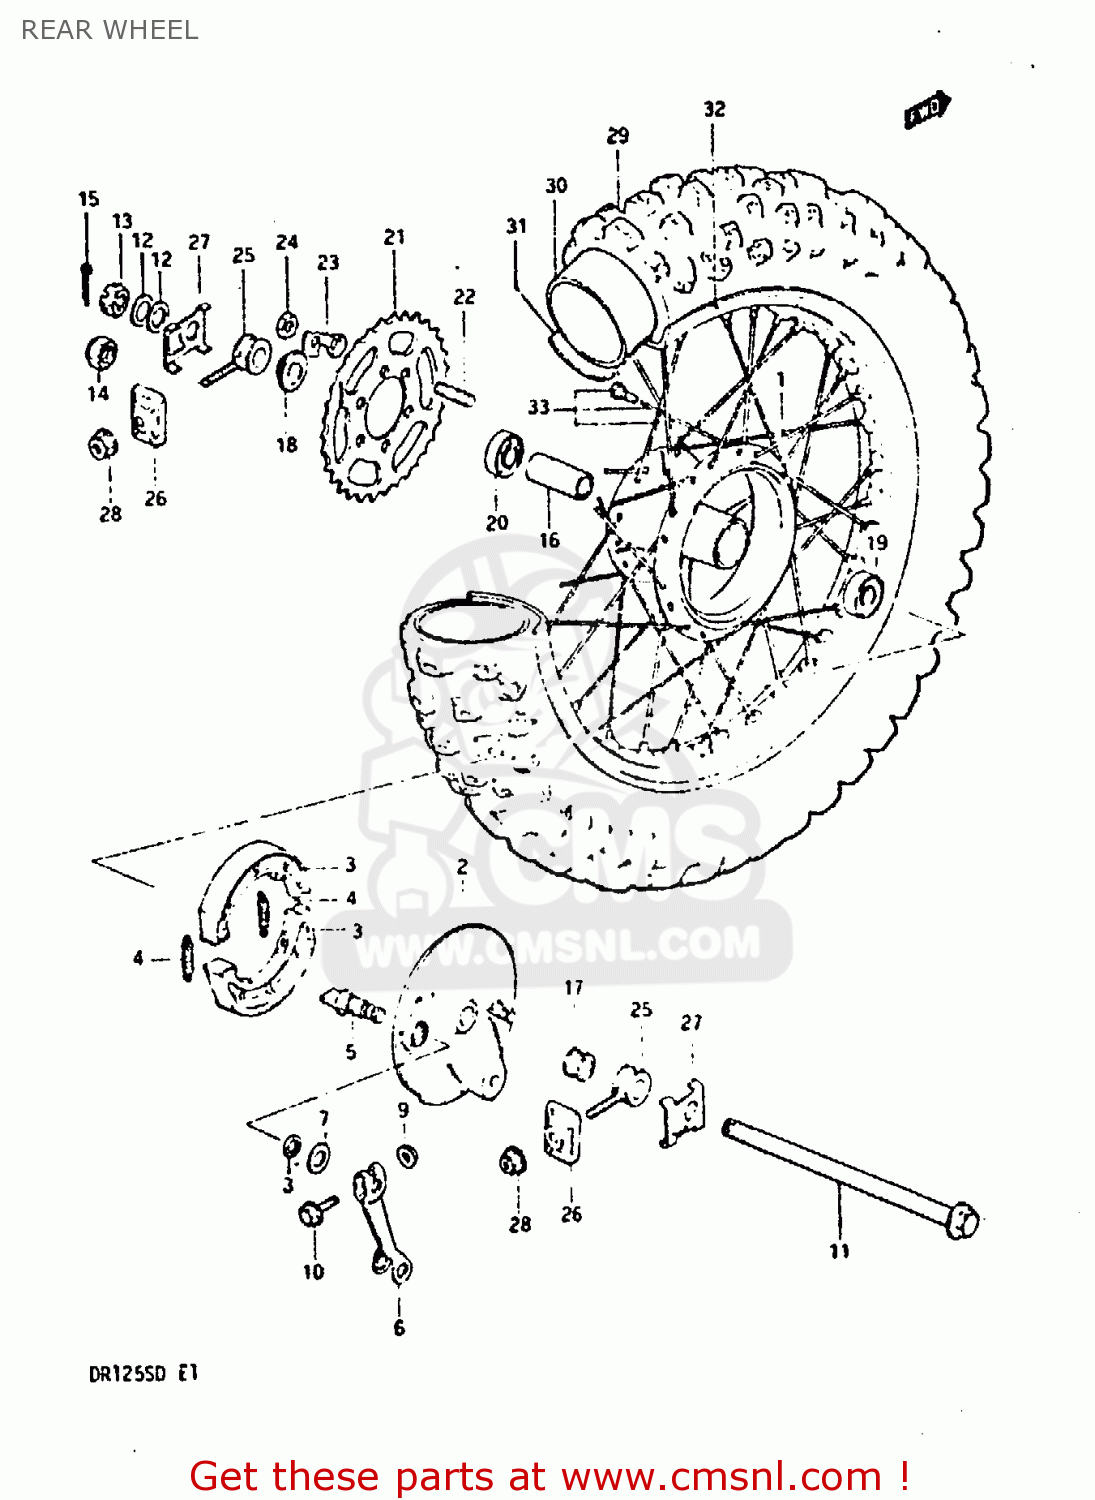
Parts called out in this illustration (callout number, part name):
1	HUB,REAR WHEEL
2	PANEL,RR BRAKE ANCHOR
3	SHOE,BRAKE
4	SPRING(L:34)
5	CAM,FRONT BRAKE
6	LEVER,RR BRAKE CAM
7	WASHER (14.5X22X1.6)
8	O-RING (D:2.4 ID:13.8)
9	NUT
10	BOLT
11	AXLE,REAR
12	WASHER
13	NUT
15	COTTER PIN
16	SPACER(15.3X21.7X107.5)
17	SPACER,RR AXLE,R
18	SPACER,REAR AXLE,LEFT
19	BEARING
20	BEARING
21	SPROCKET,RR(NT:47)
22	BOLT,STUD
23	WASHER
24	NUT
25	ADJUSTER,CHAIN
26	PLATE,CHAIN ADJUSTER
27	WASHER,CHAIN ADJUSTER GUIDE
28	NUT
29	TIRE
30	TUBE ASSEMBLY,WHEEL,INNER
31	PROTECTOR,INNER TUBE
32	RIM,REAR WHEEL
33	SPOKE SET
